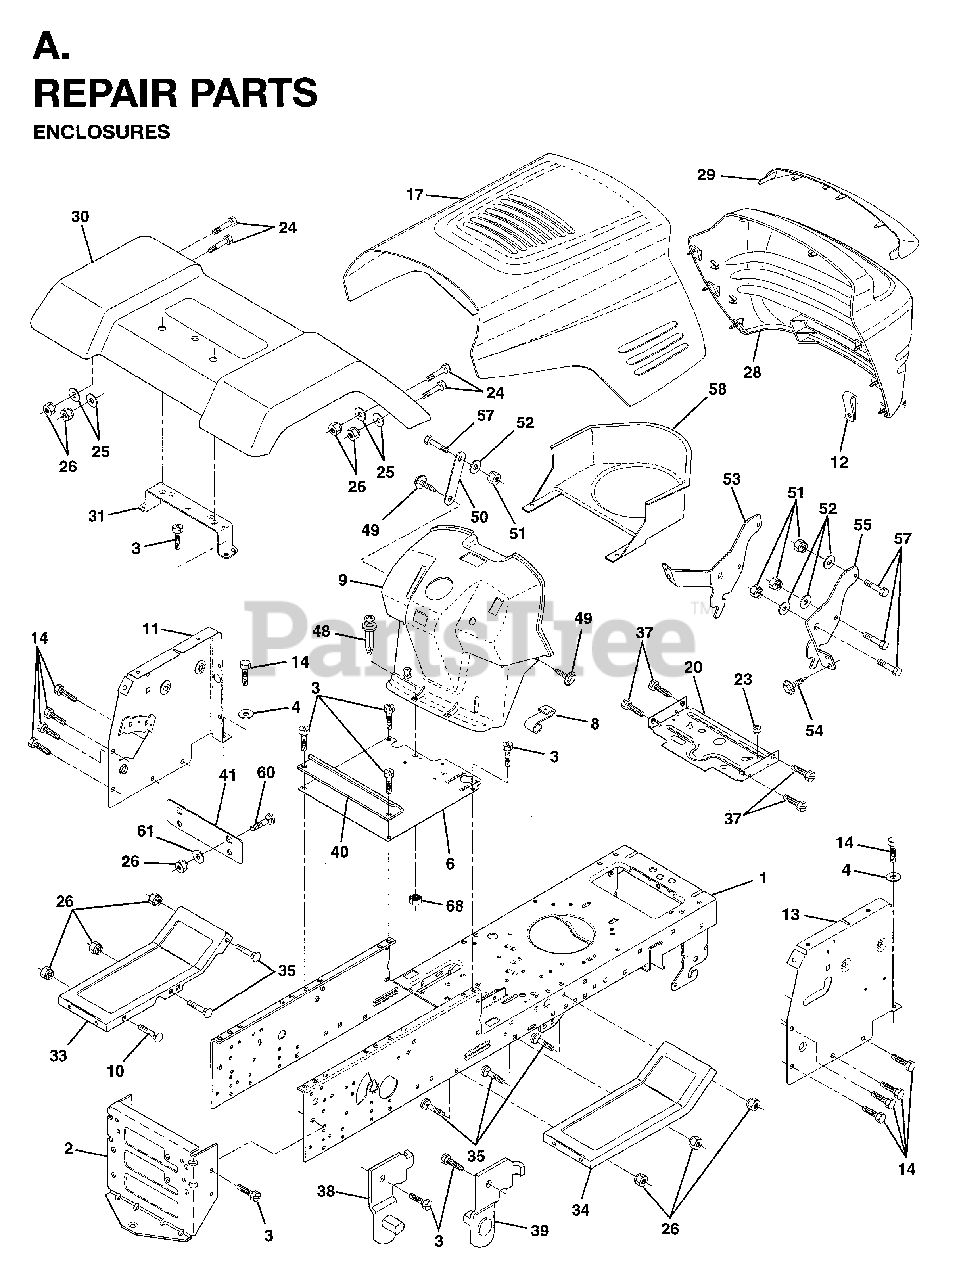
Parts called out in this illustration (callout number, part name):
2	STRETCH DRAWBAR
6	SADDLE LT FENDER
8	CLIP,INSULATOR
11	PANEL PNT DASH LH
13	PANEL DASH RH
20	PLATE MTG BATTERY FUEL TAND
23	GROMMET T
25	WASHER
26	LOCKNUT
38	BRACKET LH PIVOT
39	BRACKET RH PIVOT
41	PLATE
48	RIVET PUSH
50	BRACE
51	NUT.CROWNLOCK.1/4
58	AIR DUCT P/L/LT
59	SNAP BUSHING T
68	NUT.CROWNLOCK.1/4
